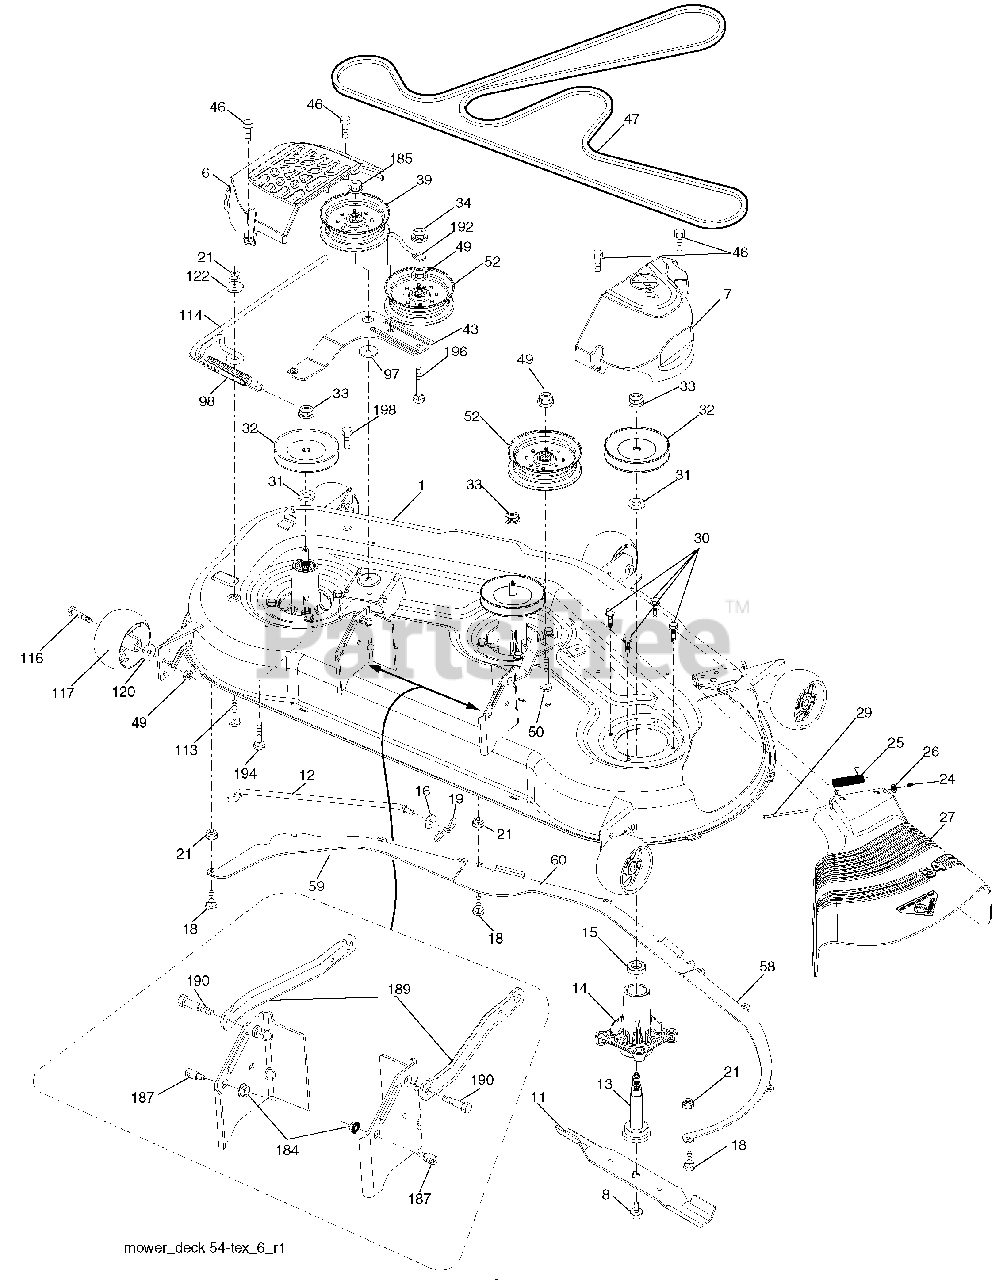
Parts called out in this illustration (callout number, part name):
1	Deck Weldment Mower
6	Cover Mandrel LH
7	Cover Mandrel RH
8	Bolt 7/16 Asm. Blade
11	Blade Discharge/Bagging
11	Blade Mulching
12	Rod-Anti Sway
13	Shaft Asm. w/Lower Bearing
14	Housing, Mandrel
15	Bearing, Ball, Mandrel
16	Washer 13/32 x 13/16 x 12 Ga.
18	Bolt 5/16-18 x 5/8
19	Pin Cotter 5/16 Bow Tie Lock
21	Nut, Crownlock 5/16-18 unc
24	Cap Sleeve
25	Spring, Torsion
26	Nut, Push
27	Deflector Shield
29	Rod, Hinge
30	Screw, Thdrol. Washer Head
31	Washer, Spacer Mower Vented
32	Pulley, Mandrel
33	Nut, Flg. Top Lock
34	Nut Crownlock 3/8-16 unc
39	Pulley, Idler 4.50 HUB
43	Arm, Idler
46	Screw, Thdrol. 1/4-20 x 5/8
47	V-Belt, Mower
49	Nut, Lock Flg. 3/8-16 unc
50	Bolt Rdhd. Sqnk. 3/8-16 unc x 2
52	Pulley Idler
58	Baffle Right
59	Baffle Left
60	Baffle Center
97	Washer Hardened
98	Spring Drive
113	Bolt Rdhd. Sqnk. 5/16-18 x 3/4
114	Rod Tension Relief
116	Bolt, Shoulder
117	Gauge Wheel
120	Washer 13/32 x 1-1/4 x 12 Ga.
122	Bushing Tension Relief
184	Nut Lock Hex Flange 5/16-18
185	Nut Lock Flange 7/16-14 Gr. 5
187	Stud Fastener w/"D" Anti-Rotation
189	Arm Susp. Mower Rear
190	Bolt Shoulder
192	Keeper Belt Idler
194	Bolt Carr. Sqnk. 3/8-16 x 2-1/4
196	Bolt Rdhd. Sqnk. 3/8-16 x 2-1/2 Gr. 5
198	Screw Thdrol. 3/8-16 x 1/2
198	Mandrel Assembly
198	Replacement Mower, Complete
